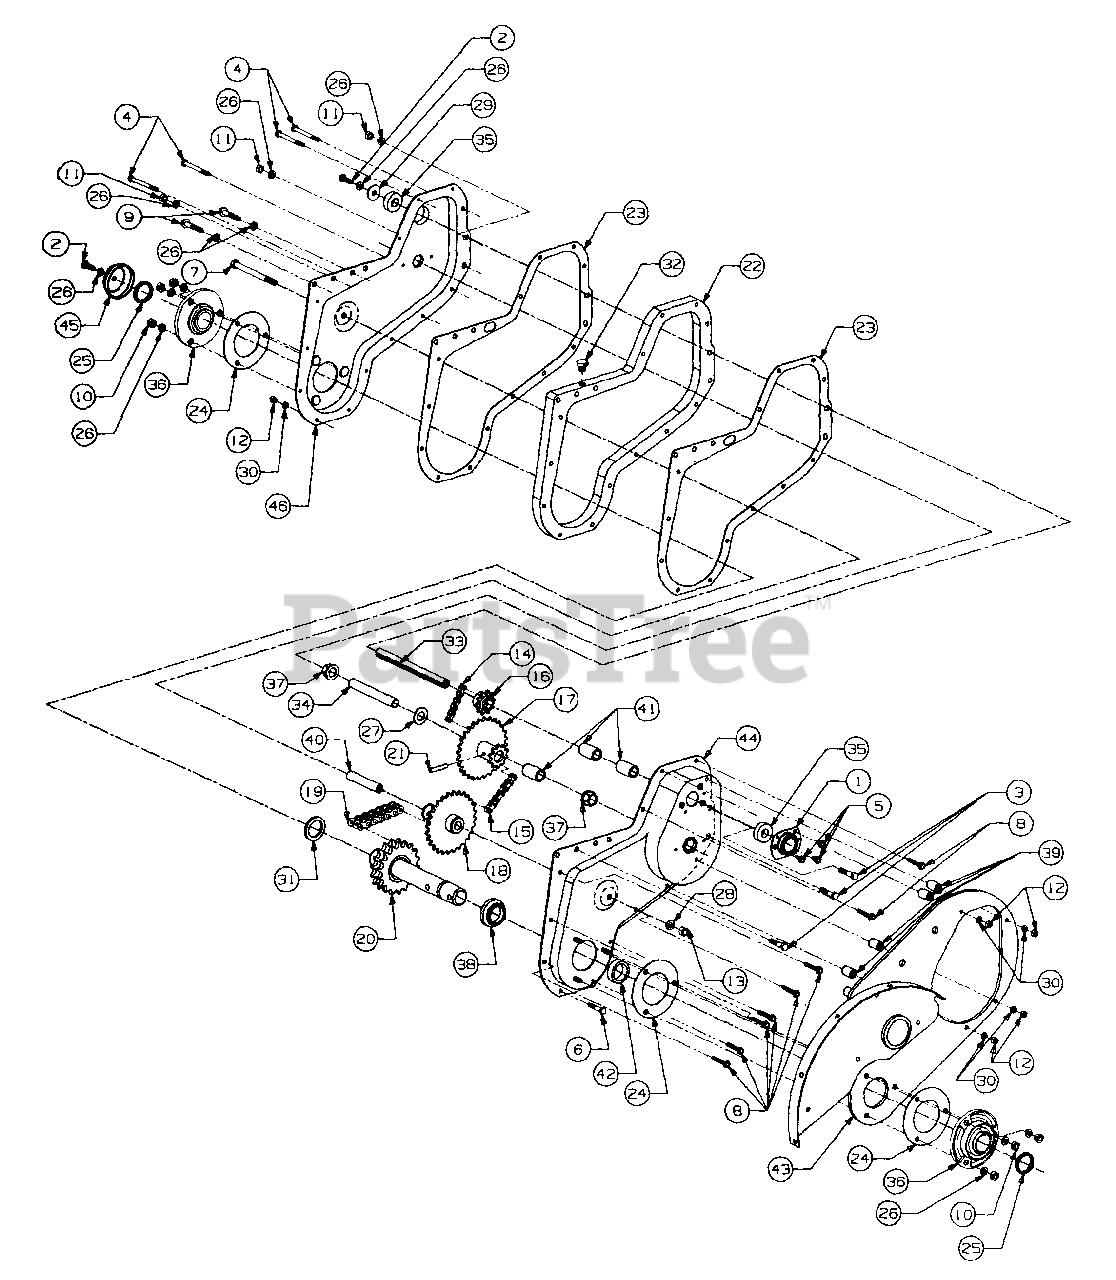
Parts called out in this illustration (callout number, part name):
1	Housing, Bearing
2	Screw, Hex Cap, 5/16-18 X .875 Lg
3	Screw, Hex Cap, 5/16-18 X 1.50 Lg GR2
4	Screw, Hex Cap, 1/4-20 X 2.75 Lg
5	Screw, Hex Wash TT-Tapp, 1/4-20 X .50 Lg
6	Screw, Hex Cap, 1/4-20 X 1.50 Lg
7	Screw, Hex Cap, 3/8-16 X 4.50 Lg
8	Screw, Hex Wash TT-Tapp, 1/4-20 X 1.50 Lg
9	Screw, Hex Wash TT-Tapp, 5/16-18 X 1.75 Lg
10	Nut, Hex Center Lock, 5/16-18
11	Nut, Hex, 5/16-18
12	Nut, Hex, 1/4-20
13	Nut, Hex, 3/8-16
14	Chain, #41 1/2 Pitch X 34 Links
15	Chain, #420 1/2 Pitch X 48 Links
16	Sprocket, 10 Tooth
17	Sprocket, 10 & 28 Tooth
18	Sprocket, 8-2 8 28 Tooth
19	Chain, #50-2 5/8 Pitch X 28 Links
20	Sprocket, Shaft w/18-2 Tooth
21	Pin, Spiral Spring, 1/4 Dia X 1.50 Lg
22	Spacer Block, Chain Case
23	Gasket, Chain Case
24	Gasket, Bearing Hsg
25	Seal, Oil
26	Washer, Lock, 5/16
27	Washer, Flat, .640 X 1.24 X .06 Thk Hdn
28	Washer, Lock, 3/8 H.D.
29	Washer, Flat, .344 X 1.125 X .063 Thk
30	Washer, Lock, 1/4
31	Washer, Special, 1.25 X 1.75 X .172 Thk
32	Plug, Vented, 1/4-18
33	Shaft, Jack
34	Shaft, Sprocket
35	Bearing, Ball
36	Housing, Bearing
37	Bearing, Hex Flange
38	Spacer, Step, 1.26 ID X 2.0 OD X .68 Lg
39	Spacer, .28 ID X .62 OD X .90 Lg
40	Spacer, .38 ID X .62 OD X 3.44 Lg
41	Spacer, .62 ID X .88 OD X 1.56 Lg
42	Spacer, 1.25 ID X 1.62 OD X .50 Lg
45	Cap, Dust
